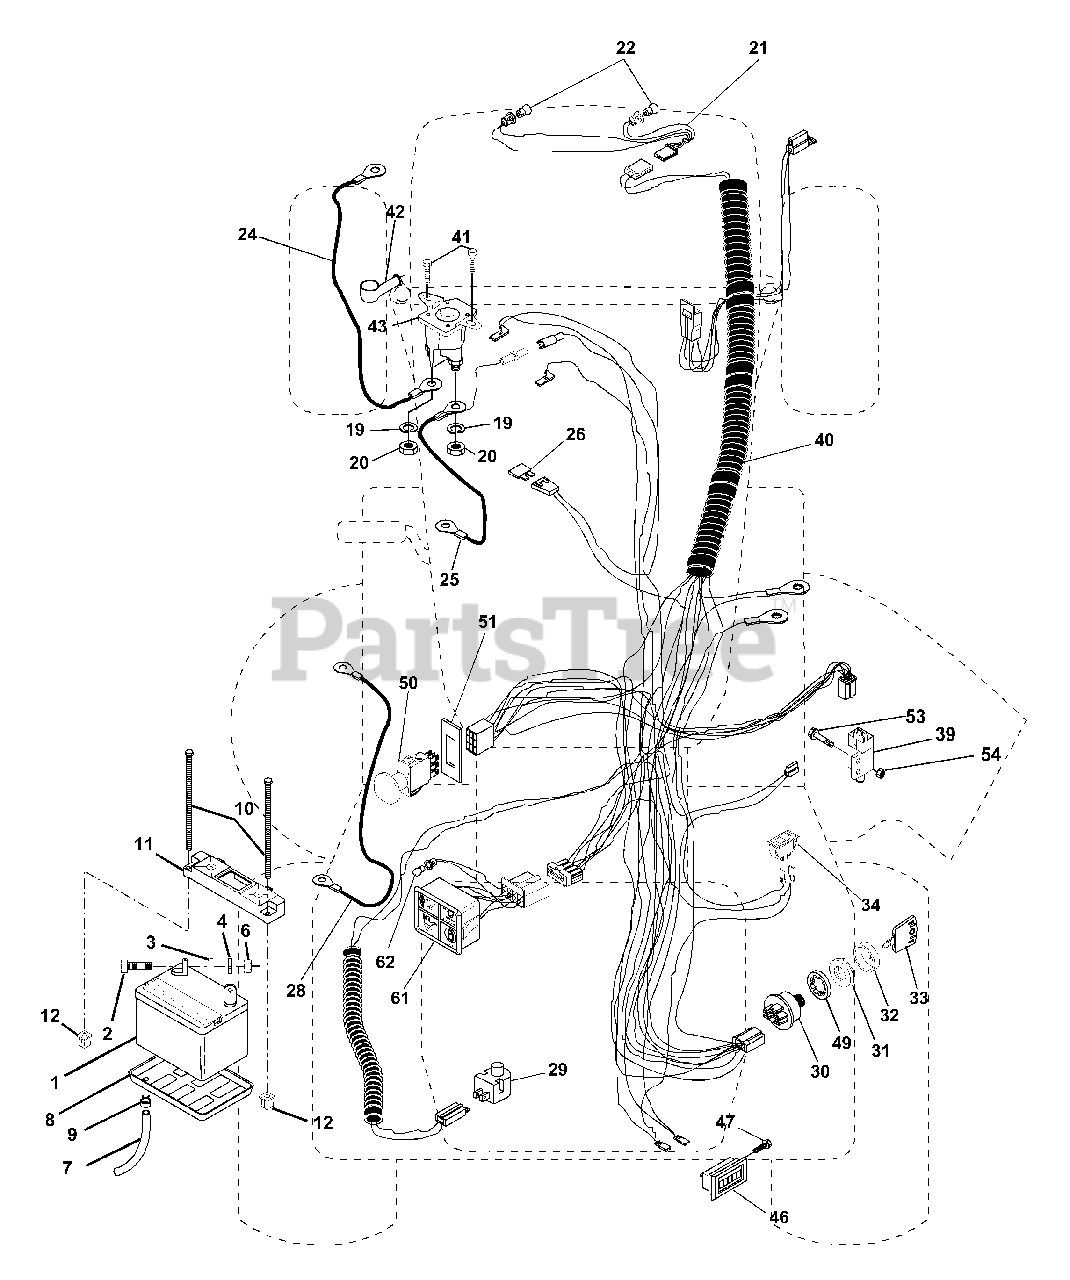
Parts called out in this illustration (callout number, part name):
1	Battery
2	Bolt Hex Head 1/4-20 x 3/4
3	Washer, Lock 1/4
4	Washer 9/32 x 5/8 x 16 Ga
6	Nut Fin Hex 1/4-20
7	Tube Plastic
8	Tray, Battery
9	Clamp, Hose
10	Bolt, Btr Frt 1/4-20 x 7-1/2 Zinc
11	Holddown Battery Dash Mount
12	Nut Push Nylon 1/4" Battery Frt.
19	Washer, Lock 1/4
20	Nut, Jam Hex 1/4-20
21	Harness Socket Light w/4152J
22	Bulb Light
24	Cable, Starter
25	Cable, Battery
28	Cable, Ground
29	Switch, Plunger
30	Switch, Ign
31	Nut, Ignition Switch
32	Cover Switch Key
34	Switch, Light
39	Intlk Switch
40	Harness Ign.
41	Screw 1/4-20 x 1/2
42	Cover, Terminal Red
43	Solenoid
46	Meter Hour
47	Screw #10-24 x 1/2
49	Washer, Lock Internal Tooth 5/8
50	Switch, PTO
51	Ring Retainer PTO
53	Screw Hex Washer Hd #10-32 x 1
54	Nut Keps #10-32
61	Light Pkg Asm
62	Bulb, Light Pkg.
